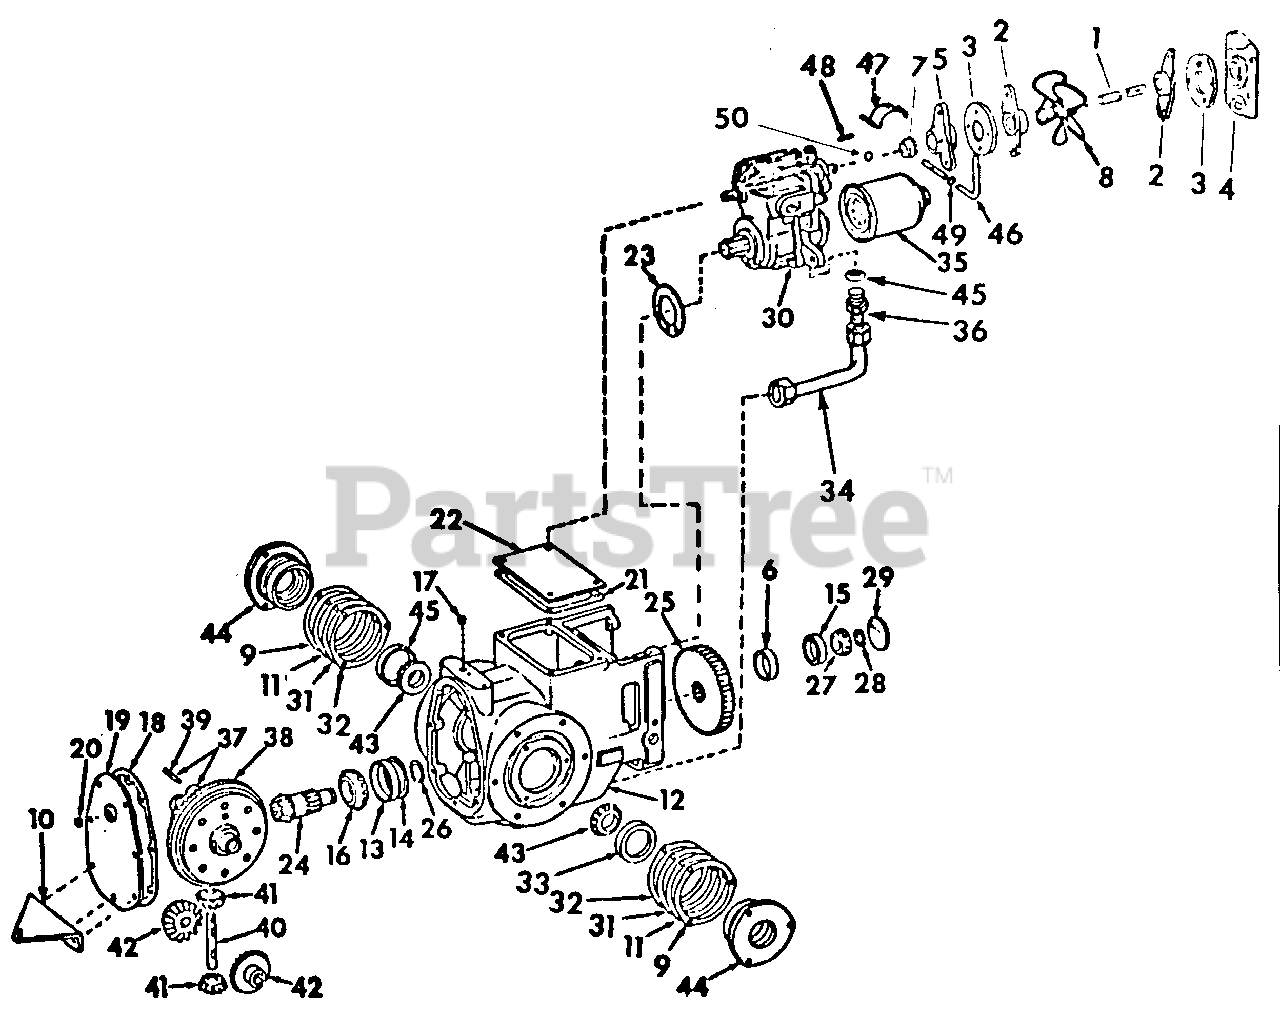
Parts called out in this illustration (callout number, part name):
1	Shaft, Drive
2	Arm, Coupling
3	Disc, Flexible Coupling
4	Flange, Drive Shaft
5	Coupler, Drive Shaft
6	Spacer, Pinion Shaft Gear
7	Bushing, Self Aligning Ball
8	Fan, Cooling
9	Shim, Bearing Retainer, .004
10	Drawbar, Fixed
11	Shim, Bearing Retainer, .007
12	Case Assy, Transmission
13	Bearing, Bevel Pinion Shaft Rear Cup
14	Shim, Rear Bearing Cup, .004
15	Bearing, Bevel Pinion Shaft Front Cup
16	Bearing Assy, Bevel Pinion Shaft Rear Cone
17	Plug, Breather
18	Gasket, Rear Cover Plate
19	Plate Assy, Rear Cover
20	Plug, 1/2-14 Auto Sq Soc Hd Drain
21	Gasket, Top Cover
23	Gasket, Front
24	Shaft, Bevel Pinion
25	Gear, Constant Mesh -66T
26	Ring, Gear Retainer
27	Bearing Assy, Bevel Pinion Shaft Front Cone
28	Ring, Pinion Shaft Front Brg Retainer, .125
29	Plug, 2-1/8 Expansion
30	Transmission Assy, Hydrostatic Drive
31	Shim, Bearing Retainer, .0149
32	Shim, Bearing Retainer, .0299
33	Bearing, Cup
34	Tube Assy, Transmission
35	Filter Assy
36	Union, 7/8-14 37 Deg Hyd Flared Tube Short Swivel
37	Case, Diff w/Drive Gear
38	Gear, Drive -46T
39	Pin, Pinion Shaft Lock
40	Shaft, Pinion
41	Pinion, 10T
42	Gear, Side
43	Bearing Assy, Cone
44	Cage Assy, Differential Bearing
45	O-Ring, 3/4 X 15/16 X 3/32
46	Handle, Dump Valve
47	Lever, Dump Valve
48	Pin, 1/8 X 3/4 C-Z Hv Coiled Spring
49	Grommet, Rubber
50	Ball, 5/8 Cr Stl
